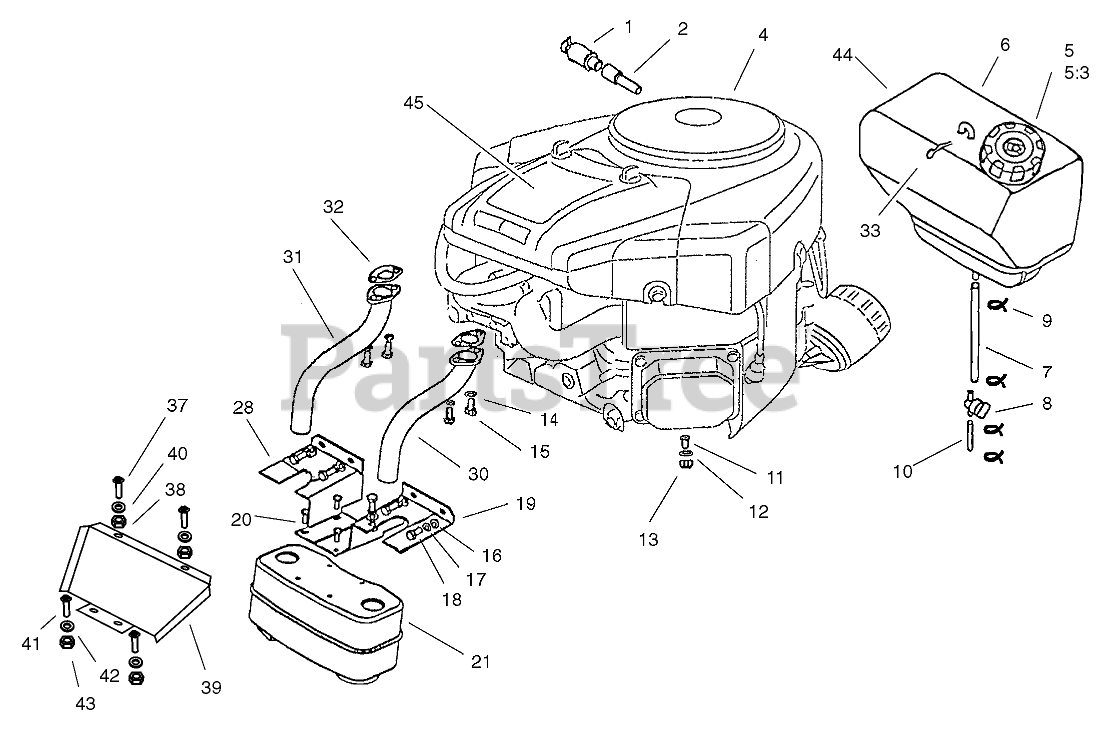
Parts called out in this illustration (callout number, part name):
1	VALVE-OIL DRAIN
2	Coupler-Oil Drain
5	GAS CAP ASM
5:3	GASKET-CAP, GAS
6	TANK-FUEL
7	LINE-FUEL
8	VALVE-TANK, FUEL
9	CLAMP-LINE, FUEL
10	LINE-FUEL
11	BOLT-HHF
12	WASHER-PLAIN
13	NUT-LOCK, NI
14	WASHER-SPRING
15	SCREW-HH
16	WASHER-PLAIN
17	WASHER-SPRING
18	SCREW-HH
19	GUARD-MUFFLER, LH
21	MUFFLER
28	GUARD-MUFFLER, RH
30	TUBE-EXHAUST, LH
31	TUBE-EXHAUST, RH
32	GASKET-EXHAUST
33	PIN-HAIR
37	SCREW-HH
38	NUT-LOCK
39	SHIELD-HEAT
40	WASHER-FLAT
42	WASHER-FLAT
43	NUT-LOCK
44	TANK-FUEL W/CAP
45	DECAL-ENGINE
